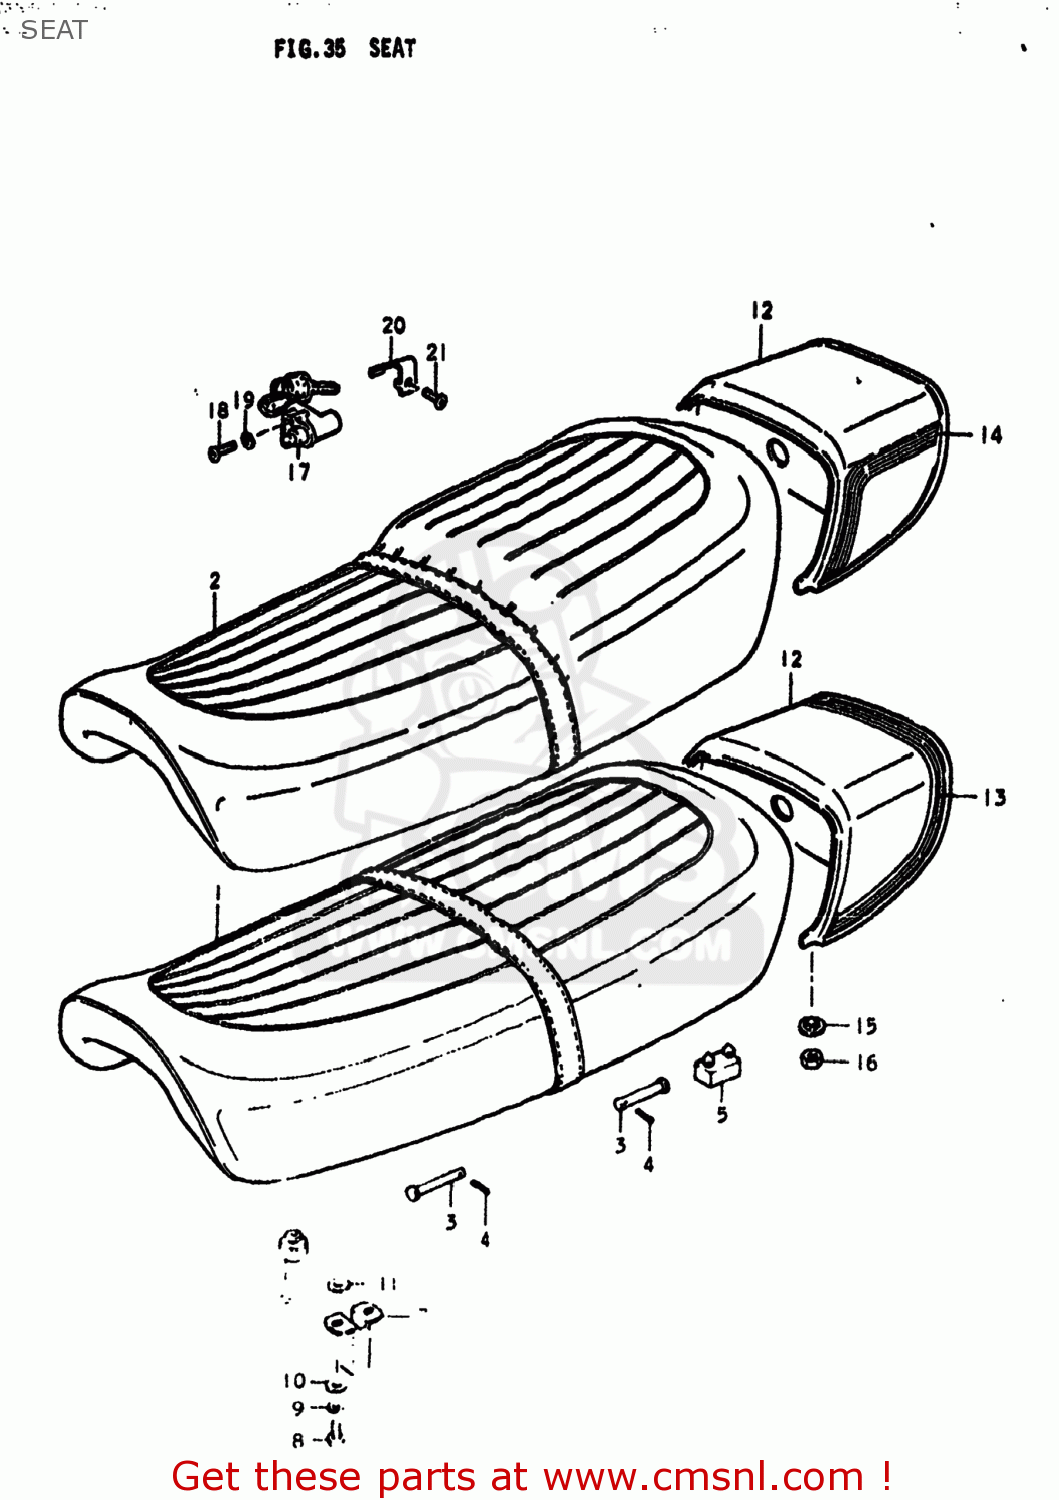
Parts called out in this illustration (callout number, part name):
1	SEAT ASSEMBLY
2	SEAT ASSEMBLY
3	PIN
4	PIN
5	CUSHION
6	CUSHION(11.5X22X20)
7	STRIKER,SEAT LOCK
8	BOLT
9	LOCK WASHER
10	WASHER
11	WASHER(8.5X18X1)
12	COVER,SEAT TAIL
14	TAPE SET, SEAT TAIL COVER
15	WASHER
16	NUT 6MM
17	LOCK ASSY,SEAT
18	SCREW
19	LOCK WASHER
20	SPRING,HELMET HOLDER
21	BOLT 5X16
